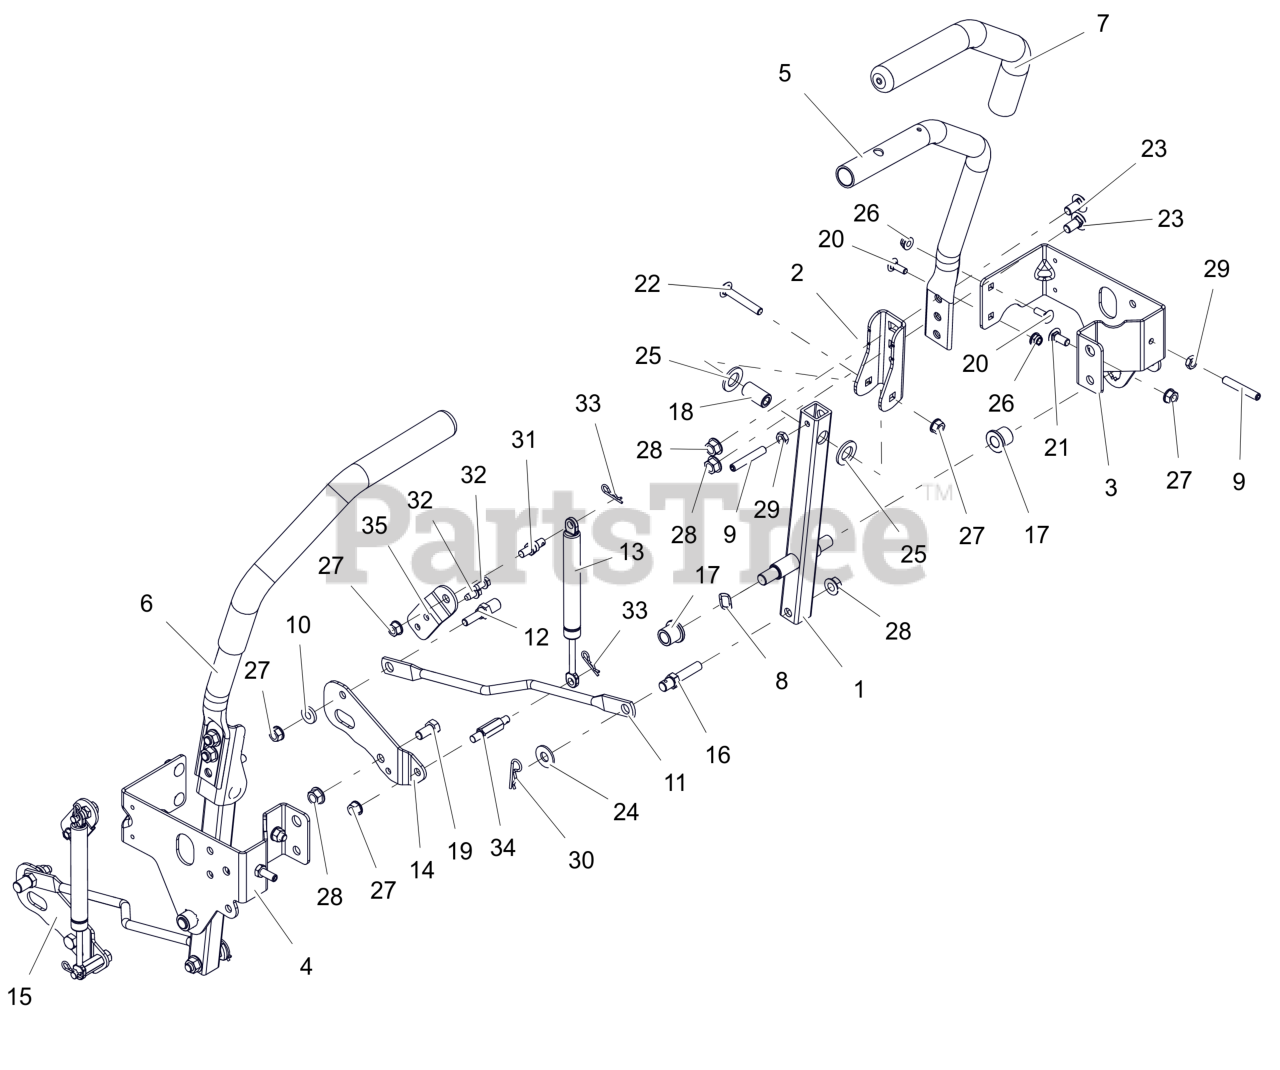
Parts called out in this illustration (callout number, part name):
1	WLDMT, LOWER CONTROL ARM (BLACK)
2	ARM, CONTROL -UPPER
3	BRKT, SPEED ADJ/SEAT PIVOT-LH (BLACK)
4	BRKT, SPEED ADJ/SEAT PIVOT-RH (BLACK)
5	WLDMT, CONTROL HANDLE -LH (BLACK)
6	WLDMT, CONTROL HANDLE - RH (BLACK)
7	GRIP, HANDLEBAR 15" FOAM
8	WAVE WASHER .531X.781X.125FH
9	SCR-SET, .312-18X2.000 SS
10	BSHG-FLG .316X.430X.225X.750
11	LINKAGE, STEERING
12	STUD, STEERING LINK-REAR
13	DAMPER, STRAIGHT MOUNT
14	PLATE, DAMPER RH
15	PLATE, DAMPER (LH)
16	STUD, STEERING LINK -FRONT
17	BHSG-FLG .500X.750X.750X.125
18	BSHG, -SLV .342 X .627 X 1.171
19	BLT,HEX .38-16X.75 G5 ZCC
20	BLT, RHSN .25-20X.750 G5 ZCC
21	BLT, RHSSN.31-18X.750 G5 ZCC
22	BLT, RHSSN .31-18X2.00 G5 ZCC
23	BTL,RHSSN .375-16 X 0.75 G5 FPB
24	WSHR,FLT .438X1.00X.083 ZCC
25	WSHR, FRICTION
26	NUT,NYL-FLG .25-20 GF ZCC
27	NUT,LK-CTR-FLG .31-18 GF ZCC
28	NUT-LK-CTR-FLG .375-16 GF ZCC
29	NUT-JAM .312-18 G2 ZCC
30	PIN, HAIR #203 .09X1.50 ZCC
31	COUPLER, DAMPER MOUNT
32	SCR-TAP .25-20X.50 HWH ZCC
33	PIN, HAIR #213 .08X1.19 ZCC
34	COUPLER, DAMPER MOUNT (LOWER)
35	PLATE, DAMPER TOP MOUNTING (BLACK)
